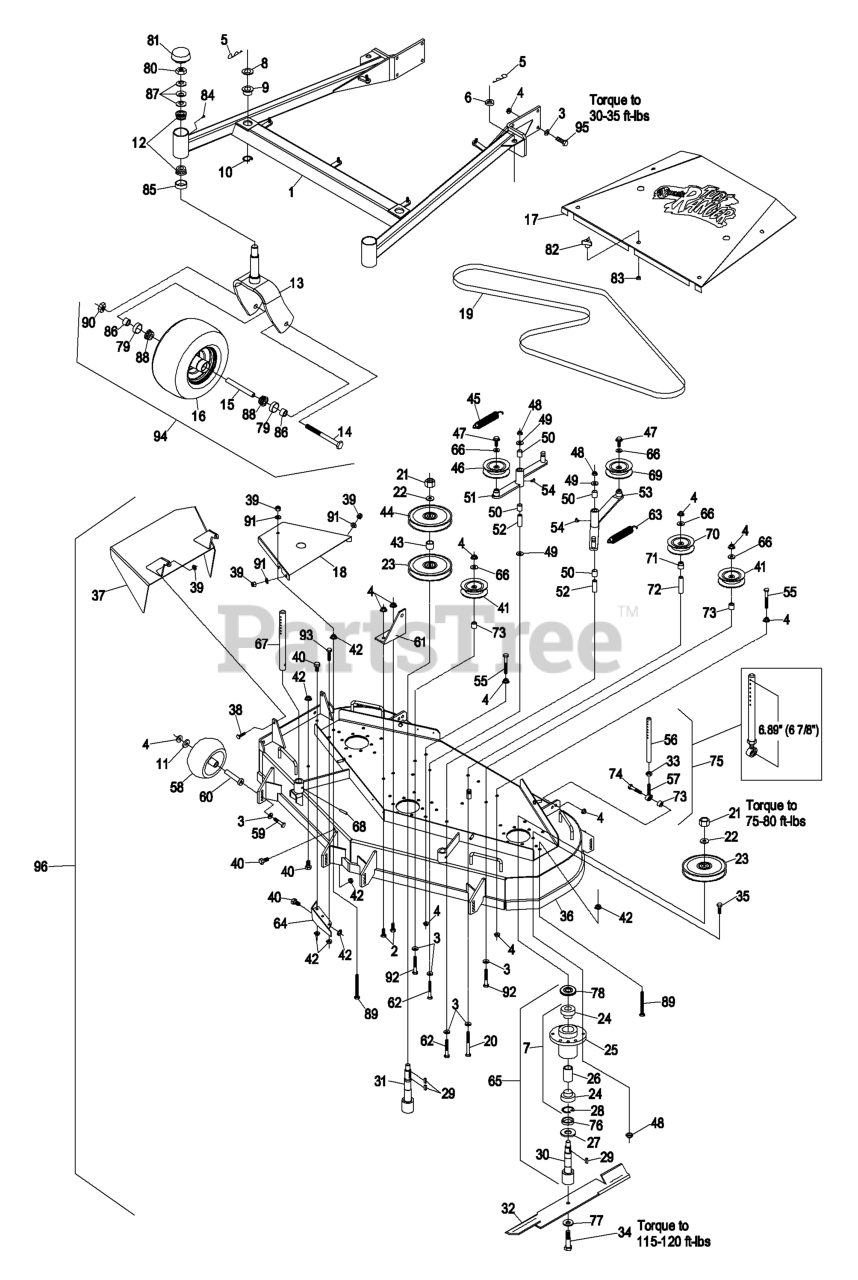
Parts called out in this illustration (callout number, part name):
1	ASM,FMD604 DK SUPPORT, SE
2	SCREW-HH
3	WASHER-BELLEVILLE
4	NUT-HHF, WHIZ
5	PIN,HAIR COTTER
8	SPACER-DECK SUPPORT
9	BUSHING-DECK
10	RING-RETAINING
12	Cone-Bearing Tapered Roller
13	WLD, CASTER FORK
14	SCREW-HH
15	SPACER,FRONT CASTER
17	KIT,SHIELD TR604 W/ DECAL
19	BELT,MULE DRIVE
20	SCREW-HH
21	NUT-HEX
22	WASHER-SPRING
23	SHEAVE,BLADE DRIVE
24	BEARING
26	SPACER-BEARING
27	GUARD-BEARING, BOTTOM
28	RING-SNAP
29	KEY-SQUARE
30	SPINDLE,SHORT
31	SPINDLE,LONG
33	NUT-HEX
34	SCREW-CAP
35	SCREW-HH
37	WLD,CHUTE FMD604
38	SCREW-HH
39	NUT-LOCK, NI
40	SCREW-HH
41	IDLER,PULLEY
43	SPACER-TUBE
44	SHEAVE,DECK DRIVE
45	SPRING-EXTENSION
46	IDLER,PULLEY
47	SCREW-HHF
48	NUT-LOCK, NI
49	WASHER-FLAT
50	SLEEVE-BEARING
51	ASM,IDLER ARM
52	BUSHING-PIVOT, IDLER
53	ASM,IDLER ARM
54	FITTING-GREASE, 90 DEG
55	SCREW-HH
56	LINK,SUPPORT
57	BALLJOINT
58	ROLLER-SCALP, ANTI
59	SCREW-HH
60	BUSHING-ROLLER
61	BRACKET,SPRING ANCHOR
62	SCREW-HH
63	SPRING-EXTENSION
64	WLD,BAFFLE DISCHARGE
65	ASM,CUTTER HSG FMD604 CEN
66	WASHER-FLAT
67	ROD,DECK SUPPORT
69	PULLEY-IDLER
70	PULLEY-IDLER
71	BUSHING,IDLER
72	SPACER-ANCHOR, CLUTCH
74	SCREW-HH
76	SPACER-PULLEY/BEARING
77	WASHER-BLADE BOLT, HEAVY
78	GUARD,BEARING TOP .880
79	SEAL-CASTER
80	NUT-LOCK, NI
81	CAP-GREASE
82	KNOB-3 PRONG
85	SEAL-GREASE
86	SPACER-BEARING
87	WASHER-BELLVILLE
88	BEARING-CONE, TAPERED ROLLER
89	BOLT,TAP HH
90	NUT-HEX
91	WASHER-FLAT
92	BOLT-CARR
93	SCREW-HH
95	SCREW-HH
96	Complete Deck Assembly
